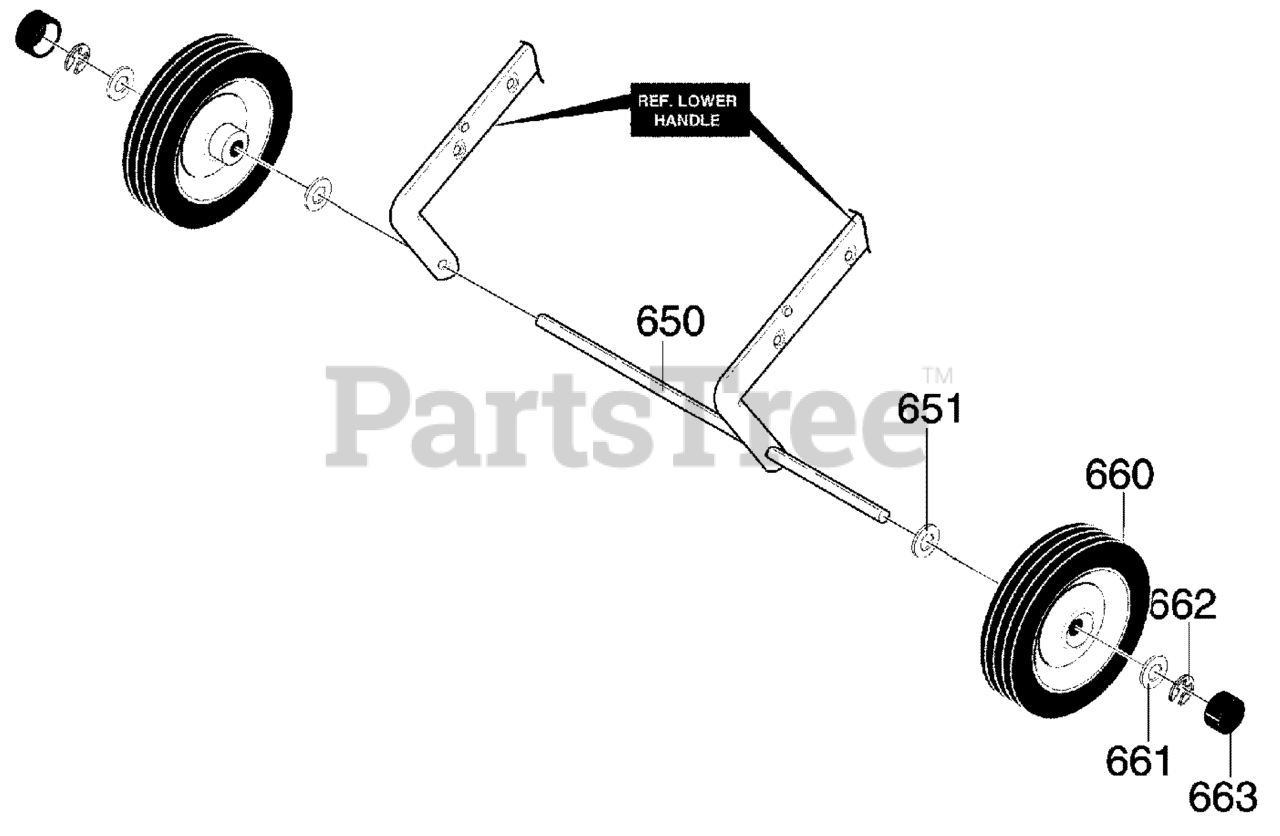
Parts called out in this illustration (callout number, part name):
650	AXLE, 7 x 1.5
651	FLATWASHER
660	TIRE & RIM
661	FLATWASHER
662	E RING
663	HUB CAP
